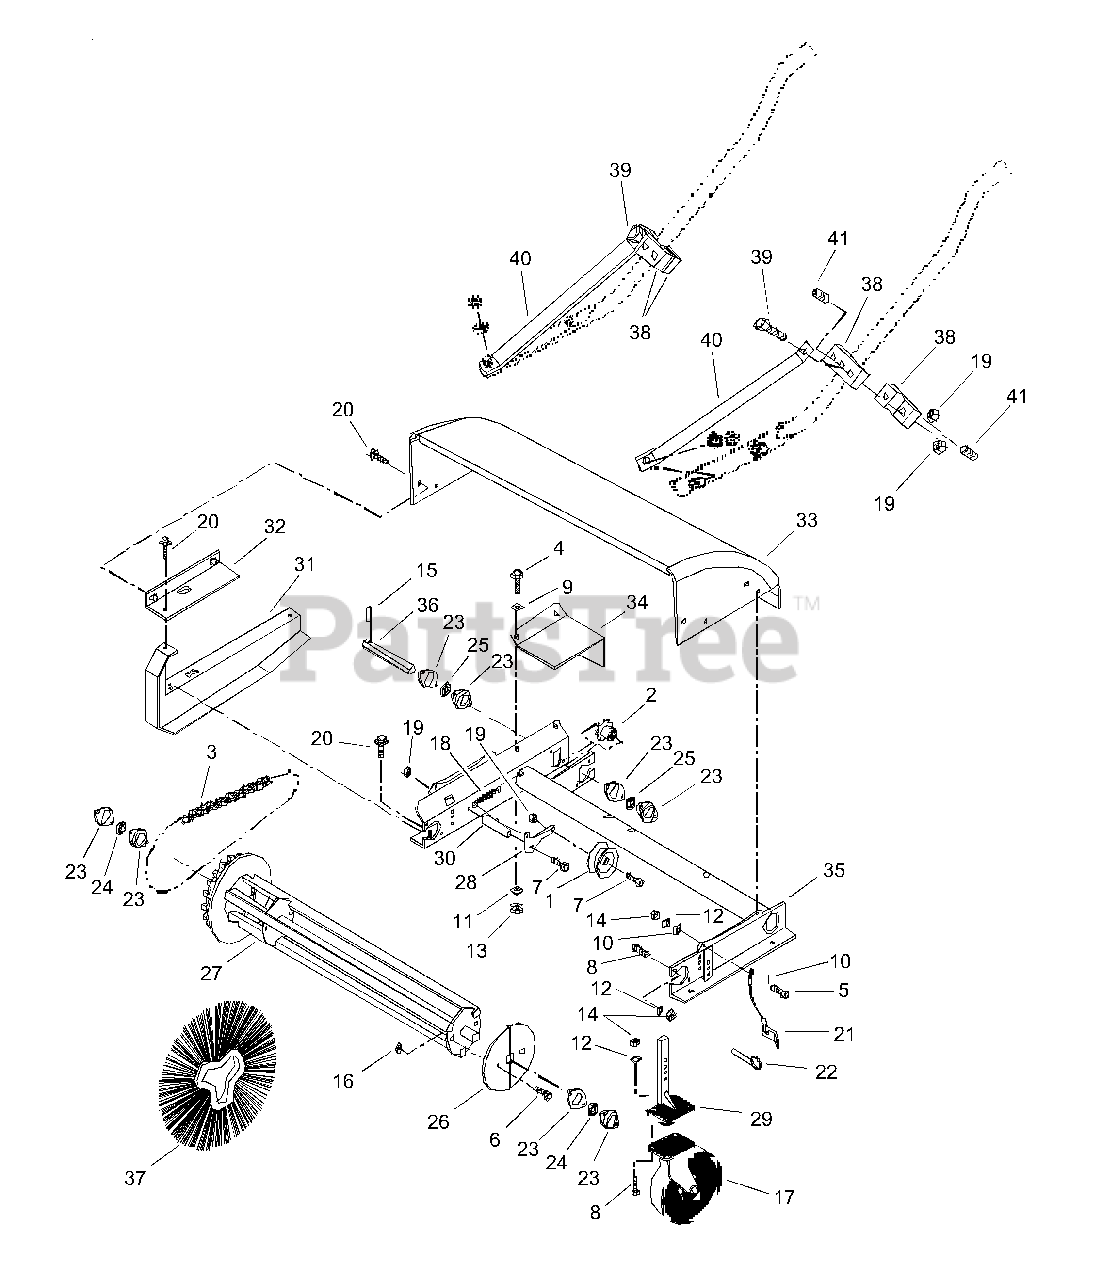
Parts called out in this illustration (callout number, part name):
1	IDLER SERVICE ASSEMBLY
2	SPROCKET
3	CHAIN, ASS'Y #40X106 EDLS W/LK
4	@BLT-HEX .25-20X.75 GR5 YWZC
5	@BLT-HEX .31-18X1.00 GR5 YWZC
6	@BLT-HEX .31-18X2.25 GR5 YWZC
7	@BLT-HEX .38-16X1.50 GR5 YWZC
8	@BLT-HEX .31-18X.75 GR5 YWZC
9	@WSHR-FL-STL.281X.62X.065 YWZC
10	@WSHR-FL-STL.312X.734X.065 YWZ
11	@WSHR-LK .25X.062 REG YWZC
12	@WSHR-LK .31X.078 REG YWZC
13	@NUT-HEX .25-20 YWZC
14	@NUT-HEX .31-18 YWZC
15	PIN, SPRING LOK .187 X 1.25
16	NUT, LOK STAMPED .312-18 TINN.
17	WHL, 5 DIA.
18	SPRING, TENSION .50 X 3.0
19	@NUT-LK-CTR .38-16 YWZC
20	SCREW, GR 10.9 M6X1-20
21	LANYARD,.06 CAB.1.25X6,TYP C
22	PIN, HITCH, .38 X 2
23	FLANGE, SPHERICAL 2"
24	BRG 1.00 BORE, SPHER. OD.
25	BRG-BALL .884HEXX52MMX1.07
26	RETAINER PLATE (SET OF 2)
27	WELD, CORE C36TW
28	ARM, IDLER,BRM C36TW
29	WELD, CASTER LEG, C36TW
30	BSHG, .62X12 GA X.75
31	SHIELD,CHAIN, ARIENS
32	SHIELD, CHAIN,TOP,ARIENS
33	KIT, HD, ARIENS
34	SHIELD, INPUT, ARIENS
35	WELD, BFRM,ARIENS
36	SHAFT, HEX 20.5, W/HOLE
37	SET,SECTION,24",P,CONV.
38	HALF-CLAMP
39	@BLT-HEX .38-16X2.25 GR5 YWZC
40	BRACE-HANDLEBAR
41	SCR-SET .31-18X.38 SKHCUPDL
